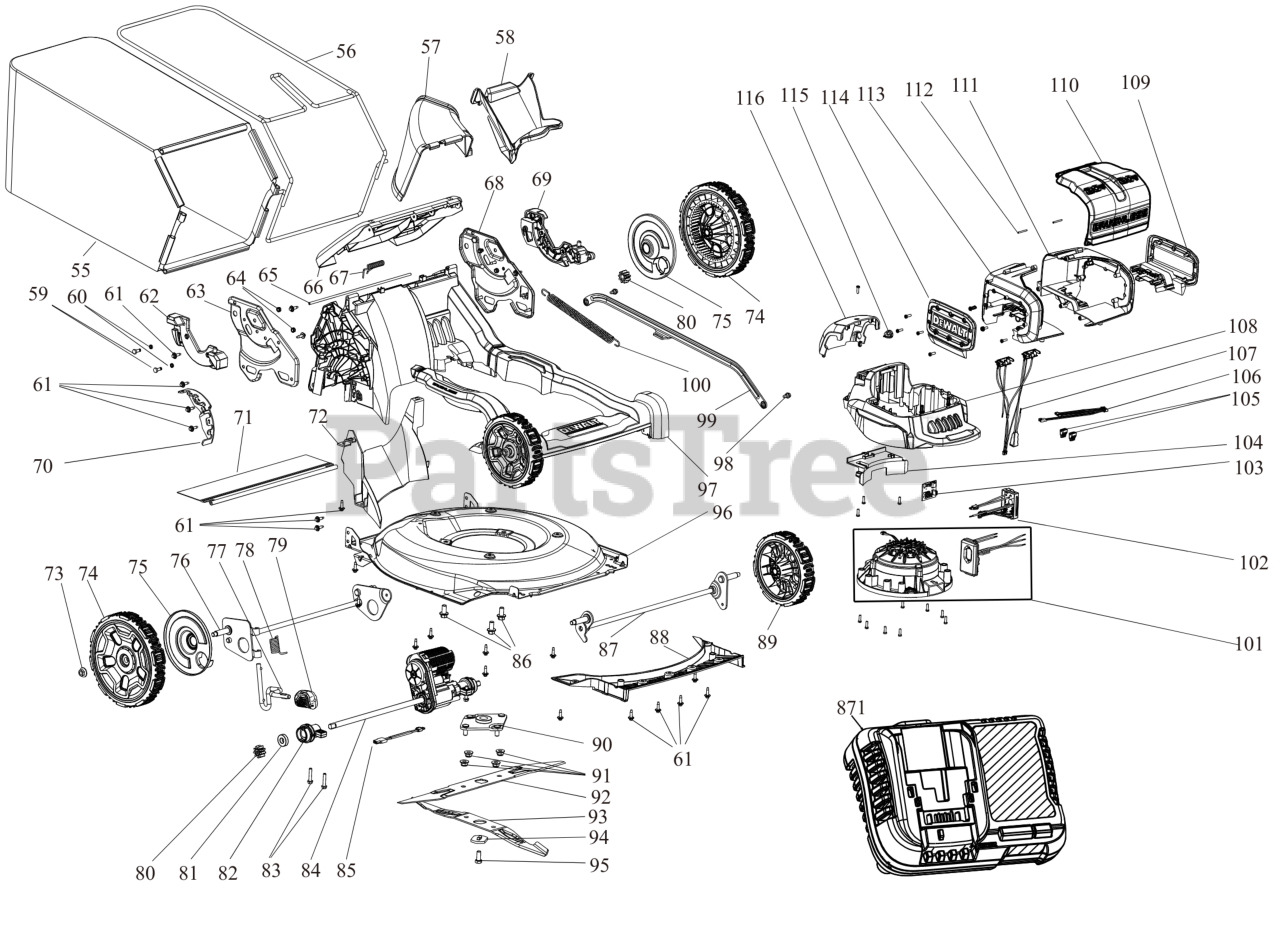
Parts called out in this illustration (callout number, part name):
1	BUTTON
2	SPRING
3	SCREW
5	COVER
6	POTENTIOMETER SA
7	CONTROL
9	BUTTOM
10	HANDLE
11	WIRE HARNESS
12	SWITCH
13	WIRE HARNESS
15	SCREW M6X45-T30-THD FRM
16	SWITCHBOX
18	HOUSING SA
19	CATCH
21	SPRING TORSION
22	WIRE HARNESS
23	PADDLE
24	PADDLE
25	PIVOT
26	COVER
27	STRIP
28	SLEEVE
29	TUBE UPPER
31	TUBE LOWER
32	SCREW M4.55X16 T20-PLAS THD FRM
33	SLEEVE
35	WASHER
36	SCREW
39	SPRING
41	SPRING
42	SPRING
43	COVER
44	DISC
45	DISC
46	SPRING
47	PIN
49	HOLDER
50	HARNESS
51	COVER
52	BUTTON
53	COVER
54	CLIP
55	GRASSBAG
56	FRAME
57	CHUTE
60	SPACER
61	SCREW 1/4-10 x .750
62	SUPPORT
63	BRACKET
64	LOCK-NUT
67	SPRING
68	BRACKET
69	SUPPORT
70	BRACKET
71	SHIELD
72	INSERT
73	FLANGE LOCK NUT
74	WHEELS
75	COVER LH
76	AXLE REAR
78	SPRING
81	BEARING
82	HOLDER
83	SCREW
84	TRANSMISSON SA
85	WIRE HARNESS
87	AXLE FRONT
89	WHEELS
90	PLATE
92	BLADE MOUNT
93	BLADE MOUNT
94	WASHER
96	PLATE
100	SPRING
101	MOTOR SA
102	MODULE
103	PCB SA
104	BAFFLE
105	CONNECTOR
106	HARNESS
107	WIRE HARNESS
108	COVER
109	PLATE SA
111	HOUSING SA
114	COVER SA
115	BUSHING
116	COVER
871	CHARGER
